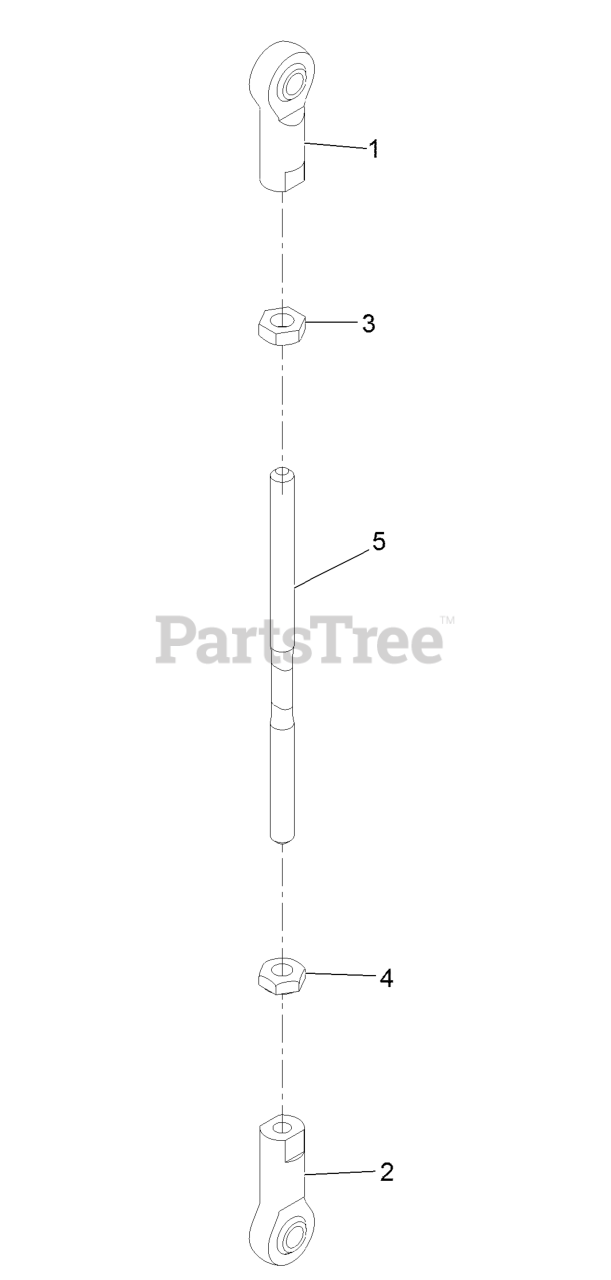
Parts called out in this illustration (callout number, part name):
1	ROD END-BALL JOINT
2	JOINT-BALL, LH
3	NUT-JAM
4	NUT-JAM
